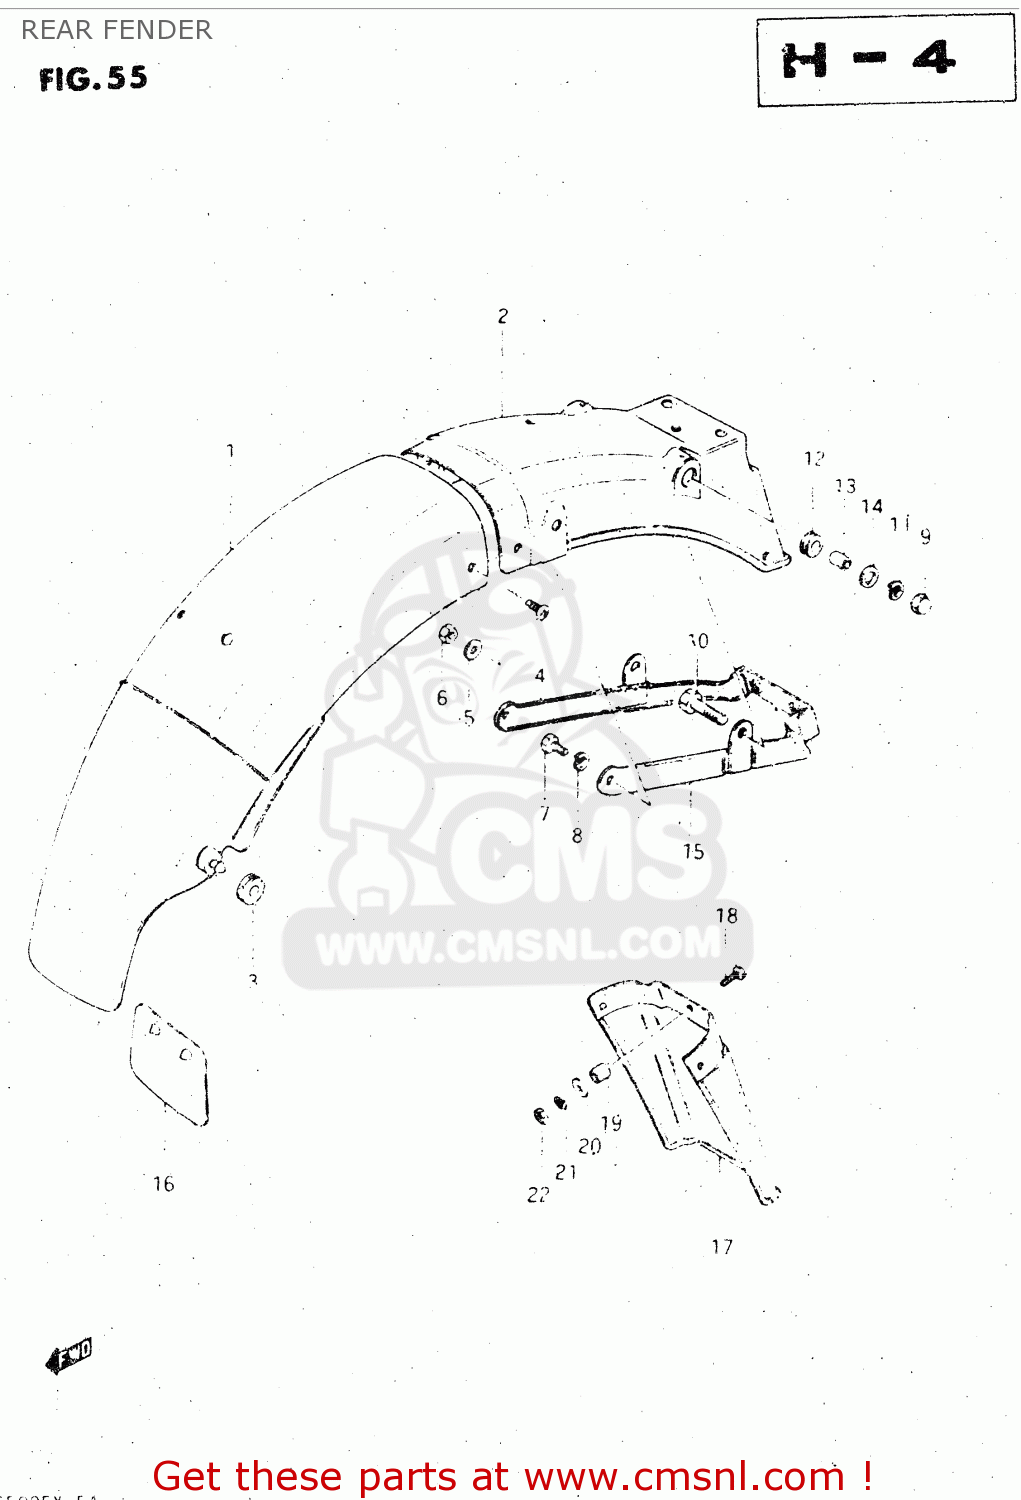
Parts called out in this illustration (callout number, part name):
1	BODY,RR FENDER FR
2	BODY,REAR FENDER,REAR
3	CUSHION
4	SCREW
5	WASHER (5.5X16X1.2)
6	NUT
7	BOLT, UPPER
8	LOCK WASHER
9	NUT
10	BOLT 8X50
11	LOCK WASHER
12	CUSHION
13	SPACER (8.2X12X7.5)
14	WASHER
15	REINFORCEMENT,REAR FENDER
16	GUIDE,RR FENDER MUD
17	EXTENSION, REAR FENDER
18	SCREW (6X15)
19	SPACER(6.2X8.3X5.7)
20	WASHER(6.5X18X1)
21	LOCK WASHER
22	NUT
